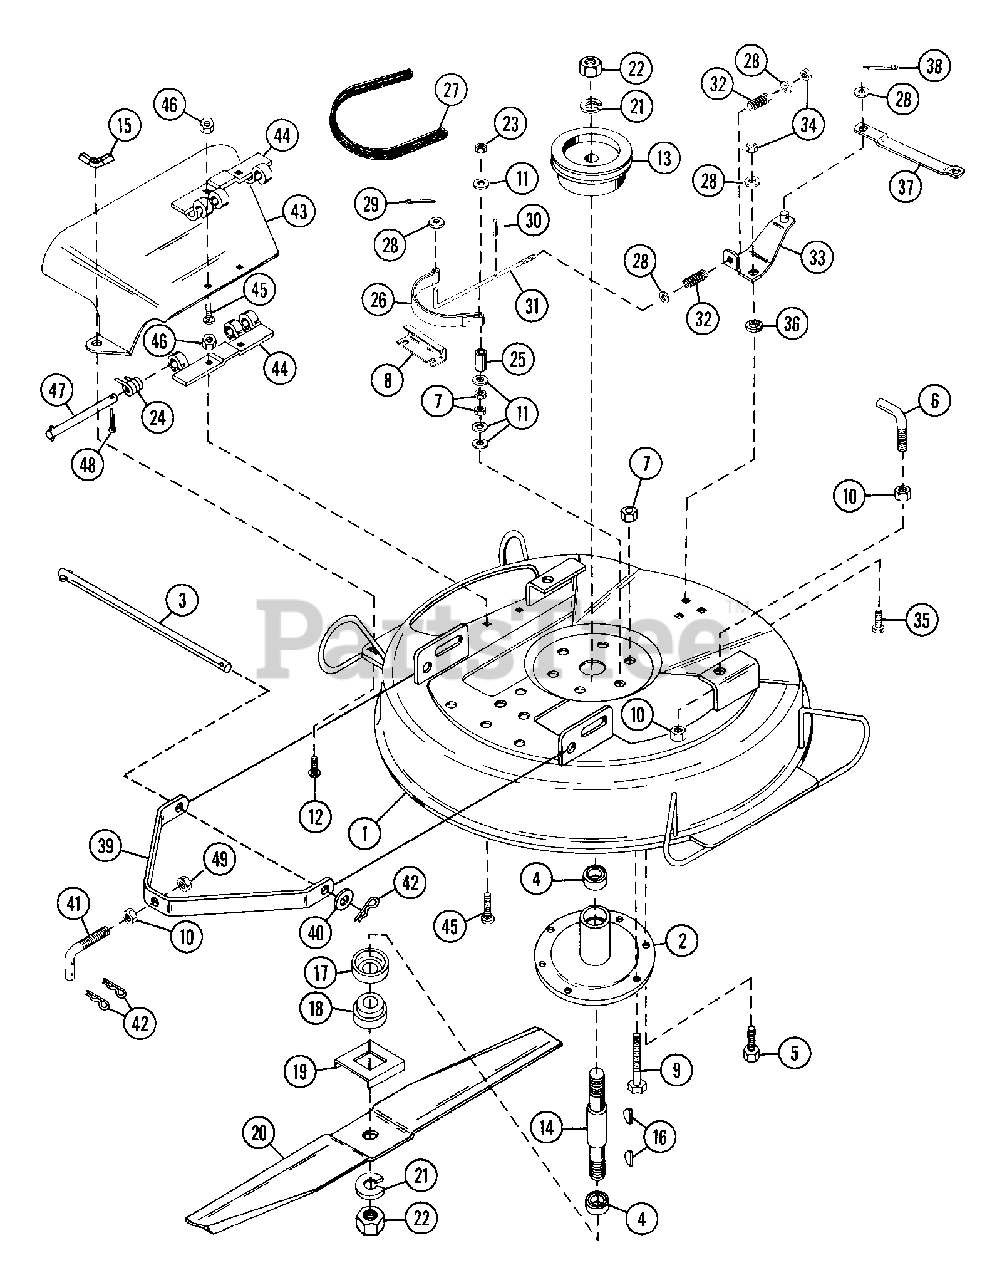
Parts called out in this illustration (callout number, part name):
1	32 INCH MOWER PAN W/DECALS
2	SPINDLE HOUSING
3	TOW PIN
4	BRG-BALL .750X1.781X.61
5	BLT-HEX .38-16X.75 PL GR5
6	HANGER HOOK
7	NUT-LK-CTR .375-16 GR A PL
8	BRAKE BAND SUPPORT
9	BLT-HEX .38-16X3.00 PL GR5
10	NUT-JAM .50-13 PL
11	WSHR-FL-STL.406X.812X.065PL
12	BLT-RDHDSQNK .25-20X.75 GR5PL
13	MOWER SHEAVE
14	SPINDLE SHAFT
15	NUT-WING .250-20
16	KEY-WDRF .188X.75X.313 SAE 9
17	BEARING SLINGER
18	RETAINER HUB
19	BLADE TRAY
20	32 IN MOWER BLADE
21	WSHR-LK .750X.188 MED PL
22	NUT-JAM .75-10 PL
23	NUT-LK-NYL .375-16 PL
24	SG-TORS .095X.50X 1.0
25	SPACER .386X.502X1.060
26	BRAKE BAND
27	V-BELT, 4L-RAW EDGE
28	WSHR-FL-STL .323X.625X.062 PL
29	PIN-COTR .06X.50
30	PIN-ROLL .125X1.00
31	BRAKE ROD
32	SG-COMP .057X.47X1.25
33	BRAKE ACTUATOR
34	NUT-LK .312-18 GR A PL
35	BLT-HEX .31-18X.75 PL GR5
36	SPACER -FLANGED .325X.498X.318
38	PIN-COTR .12X1.0 PL
39	MOWER STRAP
40	WSHR-FL-STL .505X.880X.072 PL
42	PIN-HAIR INT .09X.188 PL
43	CHUTE DEFLECTOR W/ DECAL
44	HINGE PLATE
45	BLT-RDHDSQNK .25-20X.62 PL
46	NUT-LK-CTR .250-20 PL
47	CLEVIS PIN
48	PIN-COTR .09X.75 PL
49	NUT-LK-CTR .50-13
